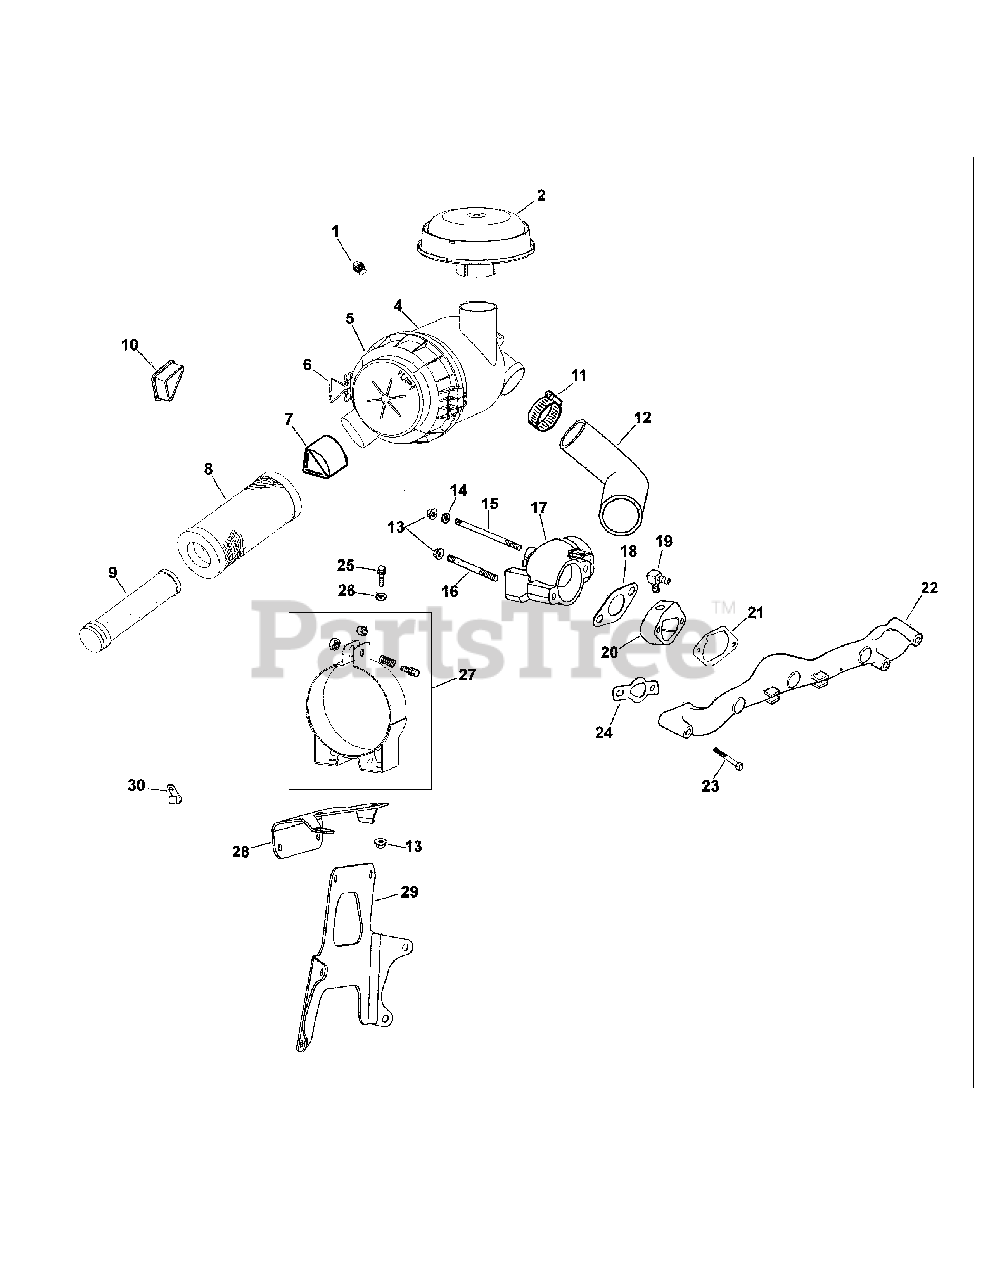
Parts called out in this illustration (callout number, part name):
2	Hood, Air Cleaner
4	Housing, Heavy Duty Air Cleaner
5	Cover Assembly, Plastic Air Cleaner
6	Clip
7	Valve, Dust Ejector
8	Element, Air Cleaner-Primary
9	Element, Air Cleaner-Safty
10	Cover, Blower Housing
12	Hose, Air Cleaner
13	Nut, Hex Lock M6x1.0x60
14	Washer, Copper 1/4"
15	Stud M6x1.0x180
16	Stud, Carburetor M6x1.0x40
17	Adapter, Elbow
18	Gasket, Air Cleaner Adapter
19	Connector, Hose
20	Adapter, Breather Fitting
21	Gasker, Air Cleaner Base
22	Manifold, Intake
23	Screw, Hex Flange M6x1.0x55
24	Gasket, Intake Manifold
25	Screw, Hex Flange M6x1.0x16
26	Washer, Plain 1/4"
27	Bracket Assembly, Air Cleaner
28	Bracket, Air Cleaner Mounting
29	Bracket, Main Support
